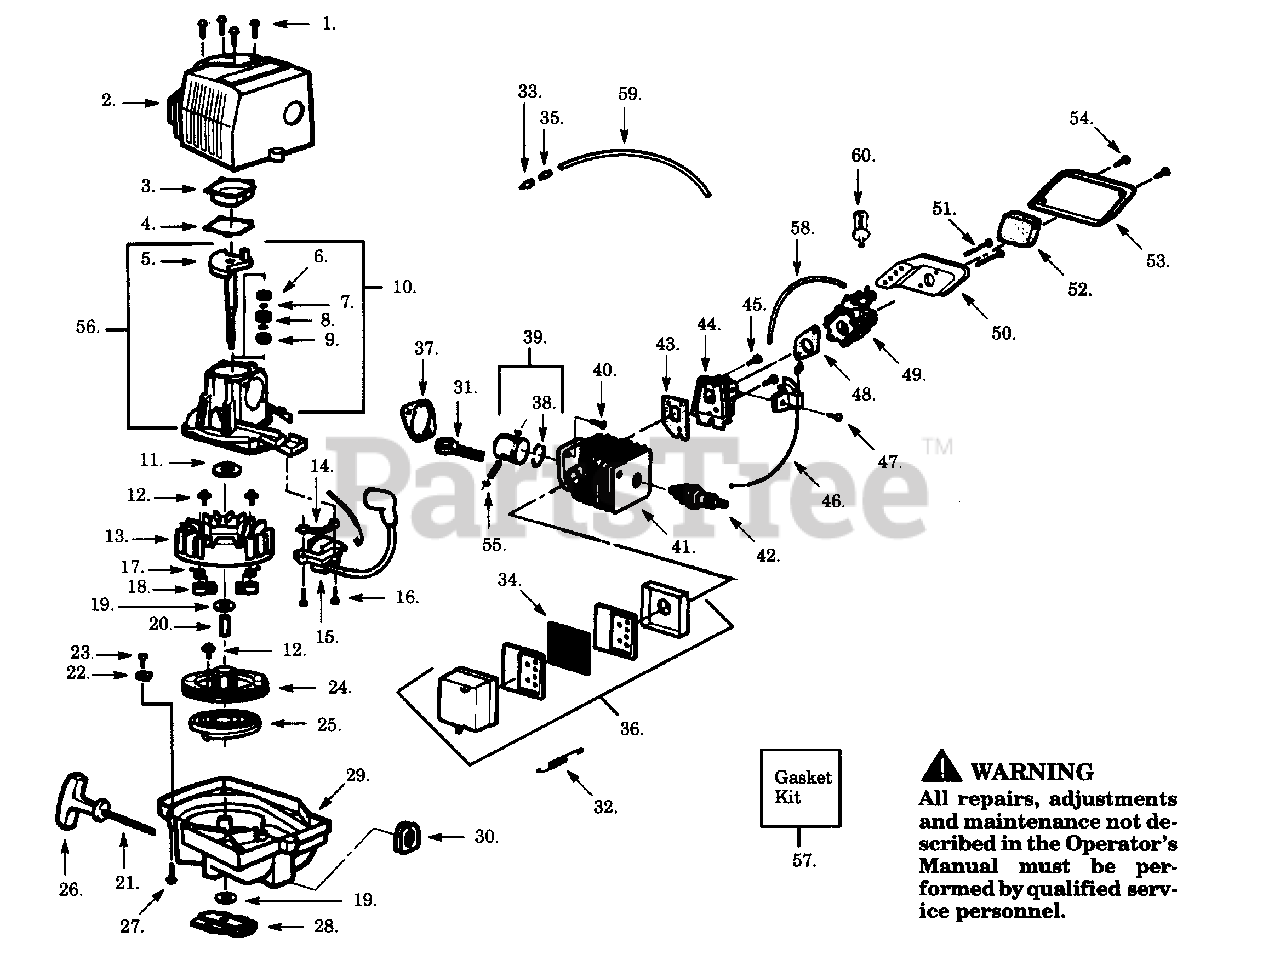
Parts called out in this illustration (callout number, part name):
3	Crankcase Cover
5	Crankshaft Ass'y.
6	Inner Bearing
7	Retaining Ring
8	Crankcase Seal
9	Outer Bearing
11	Retaining Ring
13	Flywheel Ass'y.
15	Ignition Module
17	Spring
18	Starter Dog
20	Flywheel Spacer
21	Rope Kit
22	Retainer
24	Starter Pulley Kit
25	Starter Spring
26	Starter Handle
27	Screw
28	Clutch Ass'y. Kit
29	Fan Housing
31	Connecting Rod Assy.
32	Muffler Spring
33	Check Valve
34	Muffler Screen
35	Vent Fitting
36	Muffler Kit
37	Cylinder Gasket
38	Piston Ring
39	Piston Kit
42	Spark Plug
43	Gasket
44	Carb. Adaptor
46	Throttle Cable Ass'y.
48	Gasket
49	Carburetor
52	Air Filter Foam
53	Air Filter Cover
55	Piston Pin Retainer
58	Fuel Line
59	Vent Line
60	Fuel Pick-up Ass'y.
